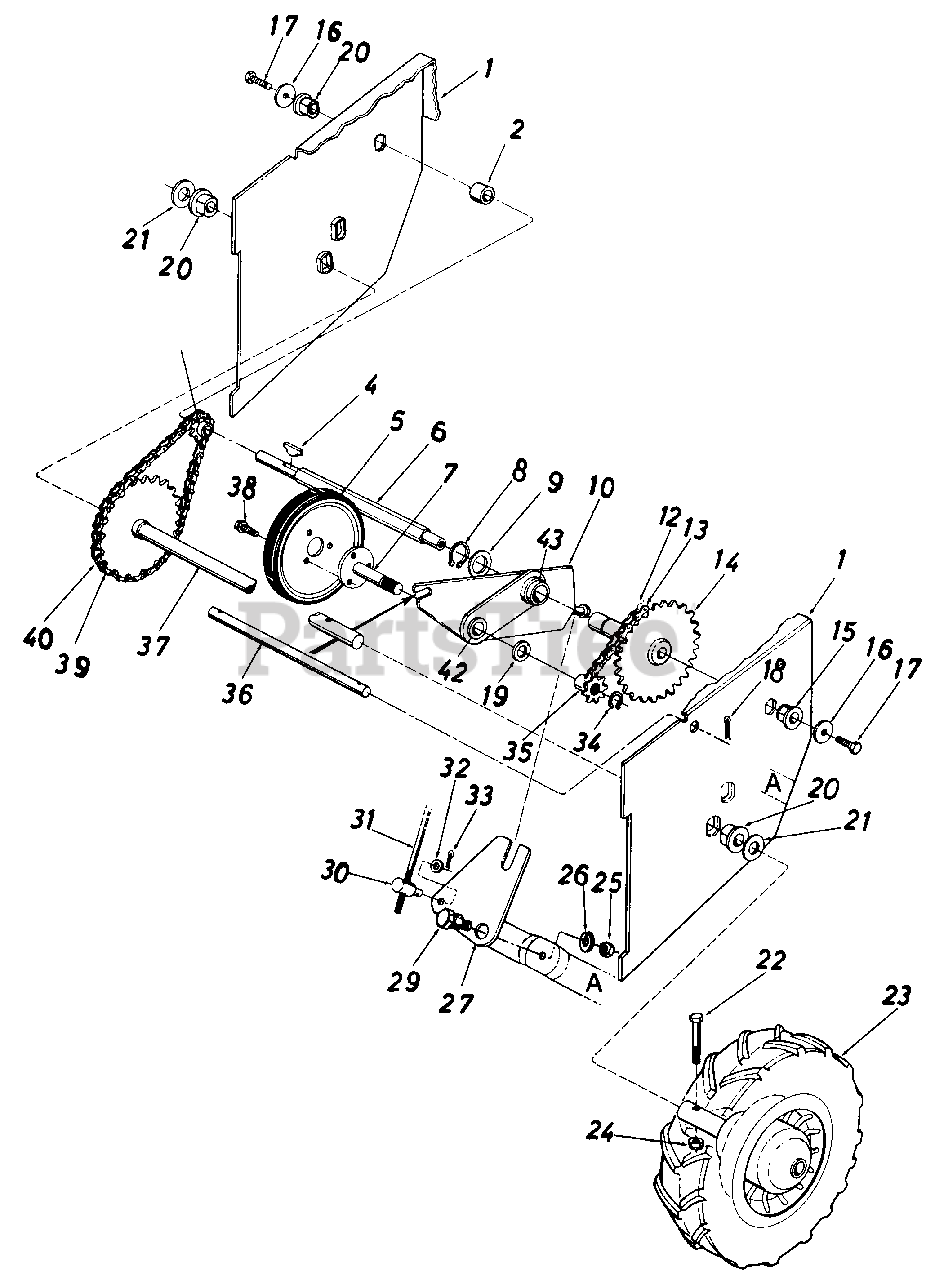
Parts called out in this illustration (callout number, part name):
1	Frame Ass'y.
2	Spacer .50" I.D. x .75" O.D. x .78" Lg.
4	#4 Hi-Pro Key 3/32 x 5/8" Dia.
5	Friction Wheel Ass'y.
6	Hex Shaft
7	Friction Wheel Mounting Plate Ass'y.
8	Snap Ring 1.00" Dia. Shaft
9	Fl-Wash. 1.03" x 1.62" O.D. x .03
10	Sliding Bracket Ass'y.
12	#41 Chain 1/2" Pitch x 35 Links
13	Master Link for #41 Chain
14	32 Teeth Sprocket Ass'y.
15	Hex Flange Brg. .630" I.D.
16	Fl-Wash. .62" I.D. x 1.00" O.D. x .06
17	Hex Lock Bolt 5/16-18 x .62" Lg.
18	Cotter Pin 3/32" Dia. x .75" Lg.
19	Fl-Wash. .62" I.D. x 1.00" O.D. x .06
20	Flange Brg. w/Flats .755" I.D.
21	Fl-Wash. .34" I.D. x 1.12" O.D. x .125
22	Hex Bolt 5/16-24 x 1.75" Lg.
23	Wheel Ass'y. Comp. - L.H. 12.5 x 3.5
24	Hex Ins. Jam L-Nut 5/16-24 Thd.
25	Hex Jam Nut 3/8-16 Thd.
26	L-Wash. 3/8" I.D.
27	Shifting Linkage Bracket
29	Shld. Bolt .625" Dia. x .170" Lg.
30	Adjustment Ferrule
31	Shifting Rod 5/16" Dia. x 32.50" Lg.
32	Fl-Wash. .34" I.D. x .64" O.D. x .06
33	Cotter Pin 3/32" Dia. x .75" Lg.
34	Snap Ring .562" Dia. Shaft
35	Sprocket 7 Teeth x .50" Pitch
36	Shaft .50" Dia. x 9.50" Lg.
37	32 Teeth Wheel Axle Ass'y.
38	Hex Wash. Hd. Self-Tap Scr. 5/16-24 x .50" Lg.
39	#420 Chain 1/2" Pitch x 39 Links
40	Master Link for #420 Chain
42	Plastic Bearing
43	Bronze Bearing
